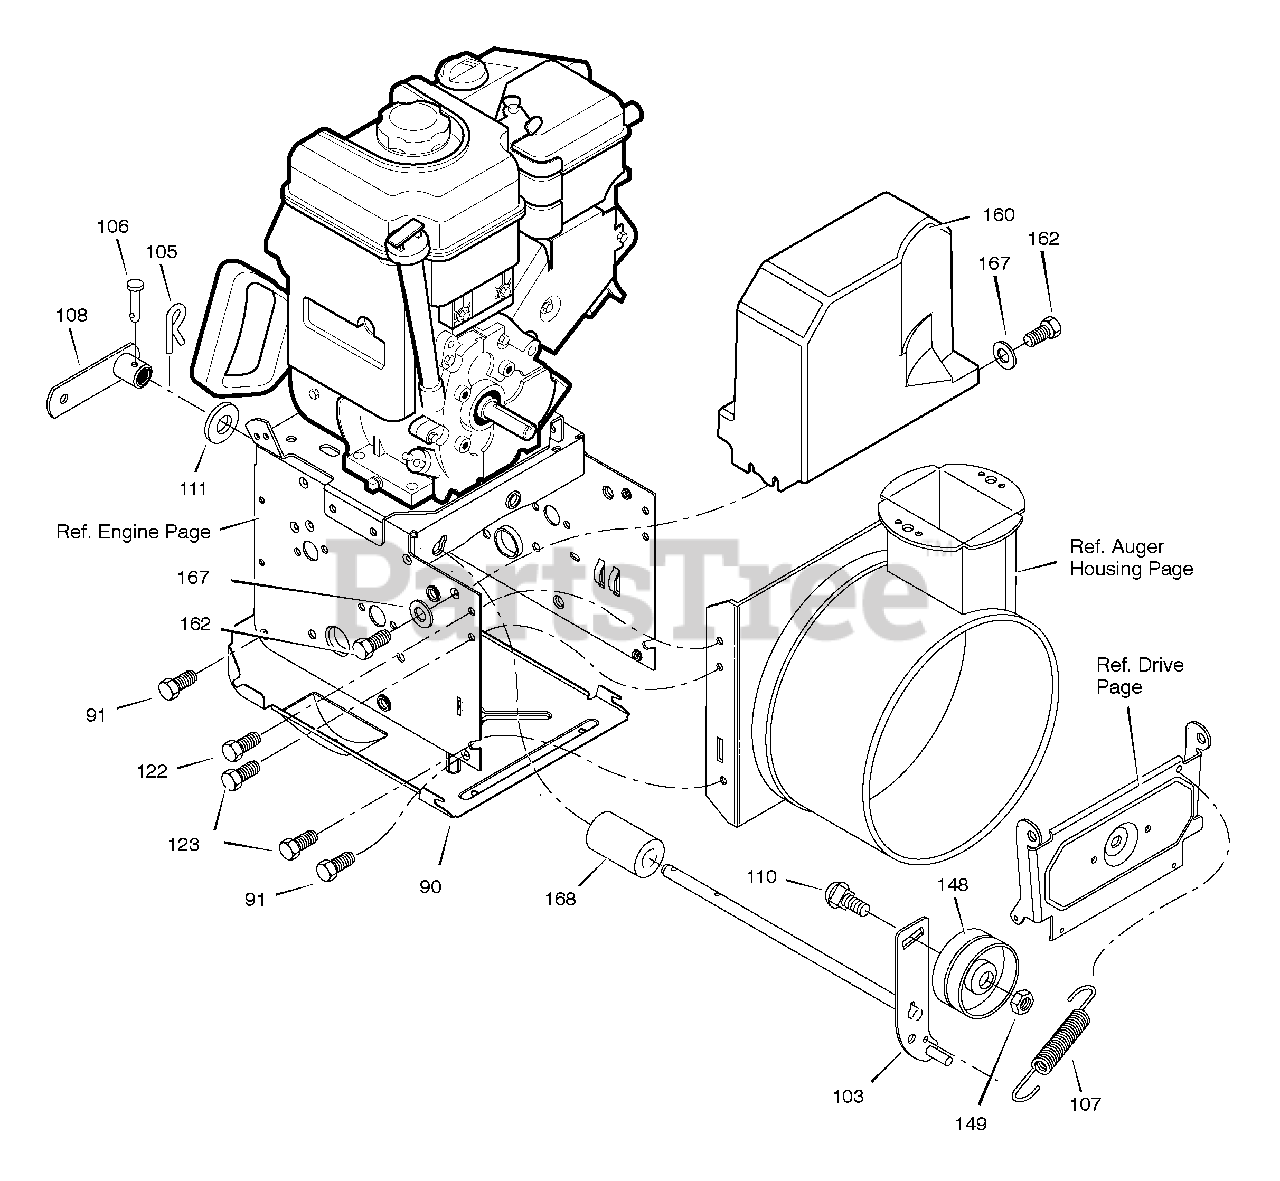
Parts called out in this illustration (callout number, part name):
90	COVER, BOTTOM
91	SCREW, 1/4-20X .63
103	IDLER ASSEMBLY, AUGER
105	PIN, HAIR .38DIAX1.64LG
106	PIN, CLEVIS 3/16" DIA
107	SPRING, TENSION
108	ASSY., SPRING ATTACH
110	BOLT, 3/8-16X1.25 CARR.
111	WASHER, FLAT
122	SCREW, TAP 5/16-18 X .50
123	SCREW, TAP 5/16-18 X .75
148	PULLEY, IDLER
149	NUT, JAM 3/8-16
160	COVER, BELT
162	SCREW, TAP
167	WASHER, FLAT
168	SPACER, AUGER BRACKET
